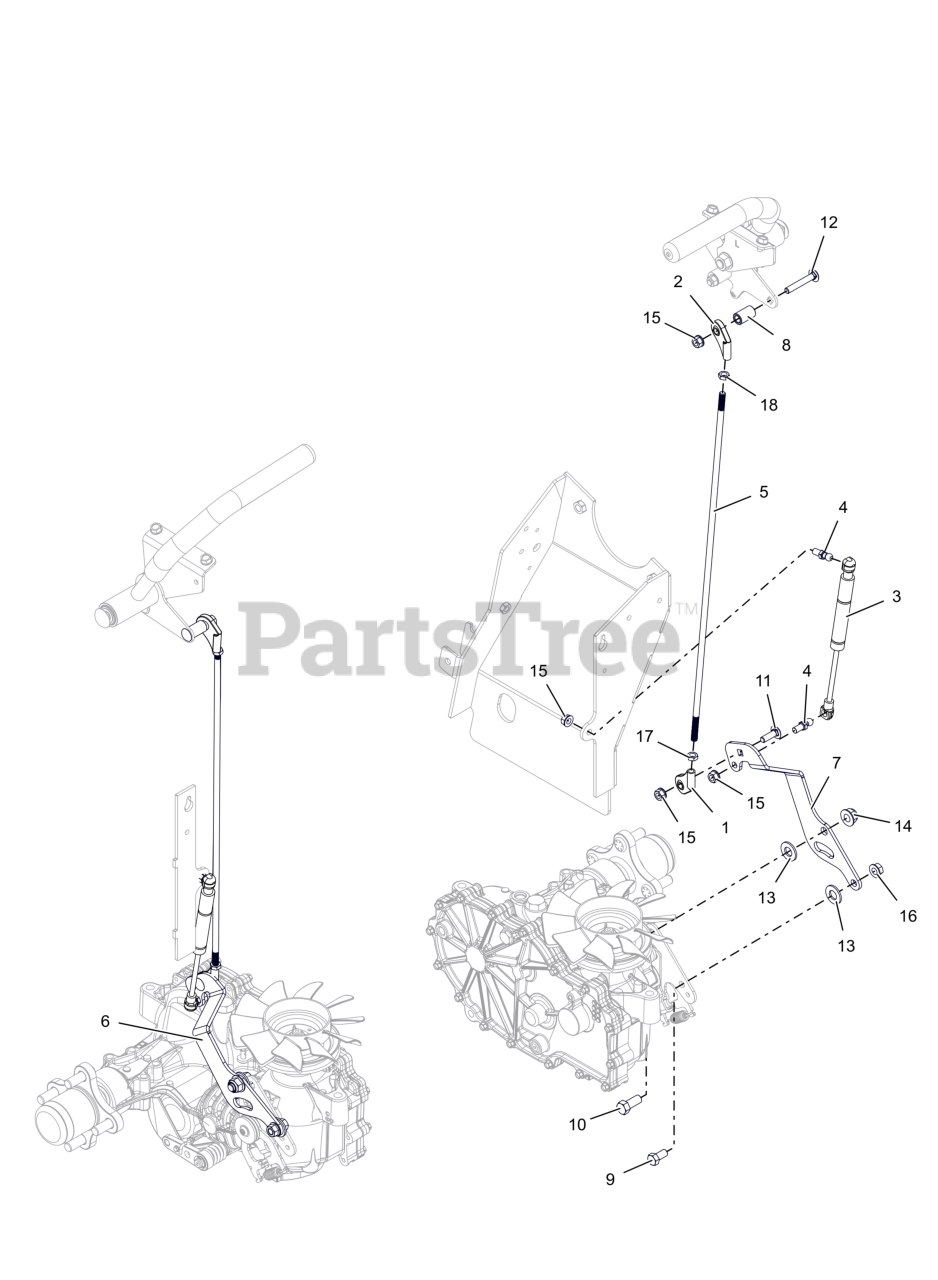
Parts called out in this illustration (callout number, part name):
1	END, ROD 5/16-24 RH
2	END, ROD 5/16-24 LH
3	DAMPER, CONTROL
4	STUD- BALL
5	ROD, STEERING
6	ARM, RH 32-36" DRIVE CONTROL (BLACK)
7	ARM, LH 32-36" DRIVE CONTROL (BLACK)
9	BLT,HEX .38-16X.75 G5 ZCC
10	BLT, HEX .44-14X1.00 G5 ZCC
11	BLT,RHSSN .31-18X1.00 G5 ZCC
12	BLT, RHSSN .31-18X2.00 G5 ZCC
13	WSHR,FLT .531X1.062X.095 ZCC
14	NUT, LK-NYL-FLG .44-14 GR5 ZC120
15	NUT,LK-CTR-FLG .31-18 GF ZCC
16	NUT-LK-CTR-FLG .375-16 GF ZCC
17	NUT-JAM .312-24 ZCC
18	NUT, JAM-LH .312-24 ZCC
